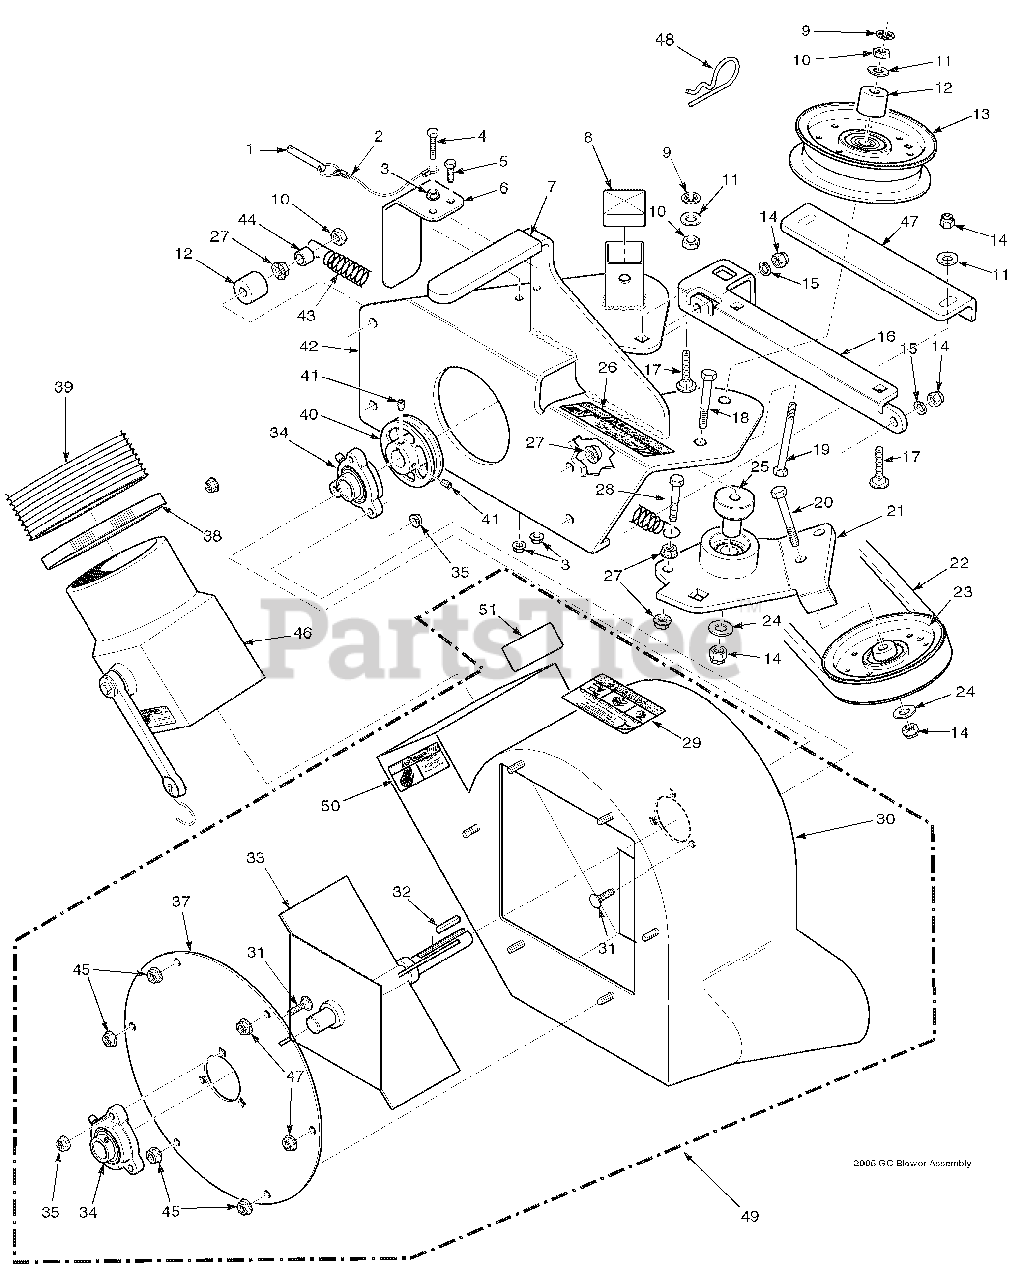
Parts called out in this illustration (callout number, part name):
1	Pin, Ring 2-1/4" Long
2	Lanyard, Deck Height Pin
3	Nut, Serr. Flange 1/4-20
4	Bolt, Hex Head 1/4-20 x 1-1/4"
5	Bolt, Hex Head 1/4-20 x 3/4"
6	Belt Cover, Rear
7	Grip, Blower Lever
8	Cap, Square
9	Nut, Push On 3/8 Thread
10	Lock Nut, 3/8-16
11	Flatwasher, 3/8-.391 x .938 x .105
12	Spacer
13	Pulley, Idler 4" Dia.
14	Nut, Elastic Stop 3/8-16
15	Lockwasher, 3/8-16
16	Plate, Catch Mounting
17	Bolt, Carr. 3/8-16 x 1-1/2"
18	Bolt, Hex Head 3/8-16 x 2-1/4"
19	Bolt, Hex Head 3/8-16 x 3-1/2"
20	Bolt, Hex Head 3/8-16 x 1-3/4"
21	Idler Arm Assembly, GC-STT 61"
22	Belt, GC-STT 61"
23	Pulley, 4" O.D., GC-STT
24	Washer, 3/8 Hardened
25	Pivot, Idler - 61" & 72"
26	Decal, Belt Cover
27	Nut, Serr. Flange 3/8-16
28	Bolt, Hex Head 3/8-16 x 1-1/2 Gr. 8
29	Decal, Danger
30	Blower Housing w/Decals
31	Bolt, Carr. 5/16-18 x 3/4" Gr. 5
32	Key, 1/4 x 1/4 x 1-1/2"
33	Fan Weldment
34	Bearing Assembly
35	Nut, Serr. Flange 5/16-18
36	Flatwasher, 5/16-.344 x .688 x .065
37	Cover, Blower Housing
38	Clamp, 8-5/8" Max Dia.
39	Hose, 8" Dia. x 56" Long
40	Pulley, 4-3/4" O.D. - 1" Bore
41	Set Screw, 5/16-18 x 3/8"
42	Frame, Blower Mount - 61"
43	Spring, Main Drive
44	Spacer
45	Nut, Serr. Flange 5/16-18
46	Adapter w/Strap
47	Plate, Blower Catch
48	Hair Pin Cotter, .243 x 4"
49	Blower Housing Assembly, GC-STT
50	Decal, Rotating Blower
51	Decal, Blower
